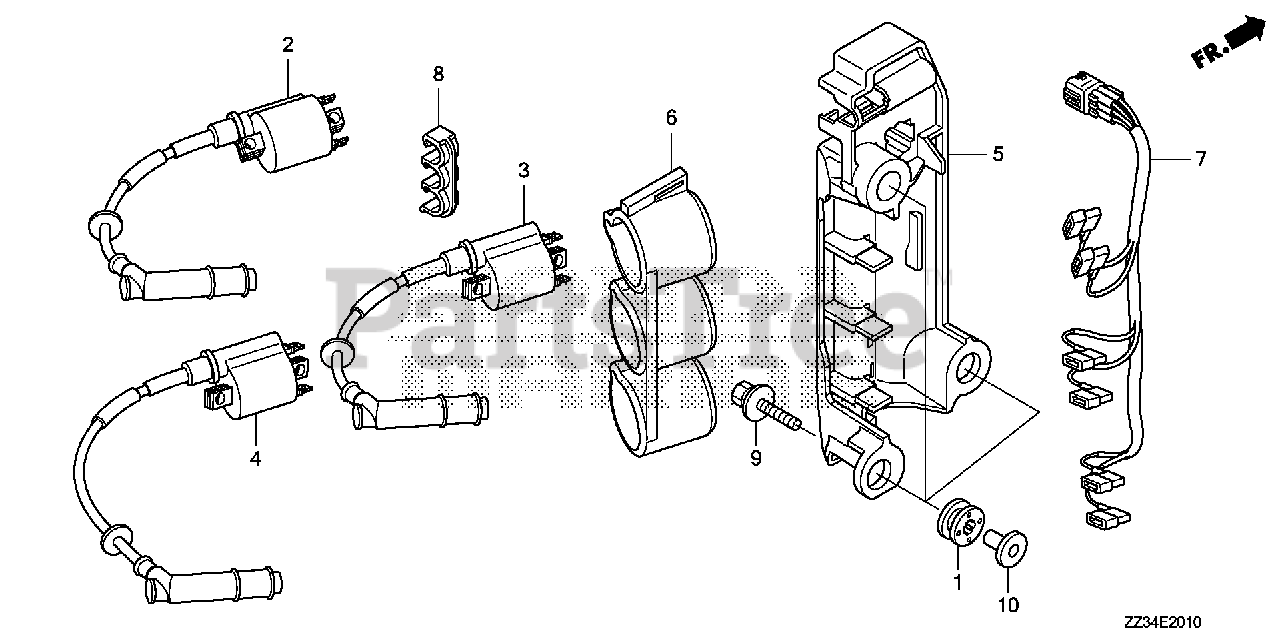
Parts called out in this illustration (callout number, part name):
1	GROMMET, ELECTRONIC PARTS CASE
2	COIL, IGNITION (1)
3	COIL, IGNITION (2)
4	COIL, IGNITION (3)
5	CASE, IGNITION COIL
6	SUSPENSION, IGNITION COIL
7	WIRE ASSY., IGNITION COIL
8	CLAMP, IGNITION WIRE
9	BOLT-WASHER (6X27) (CT200)
10	COLLAR, MODULE IGNITION CONTROL CASE (CDI)
